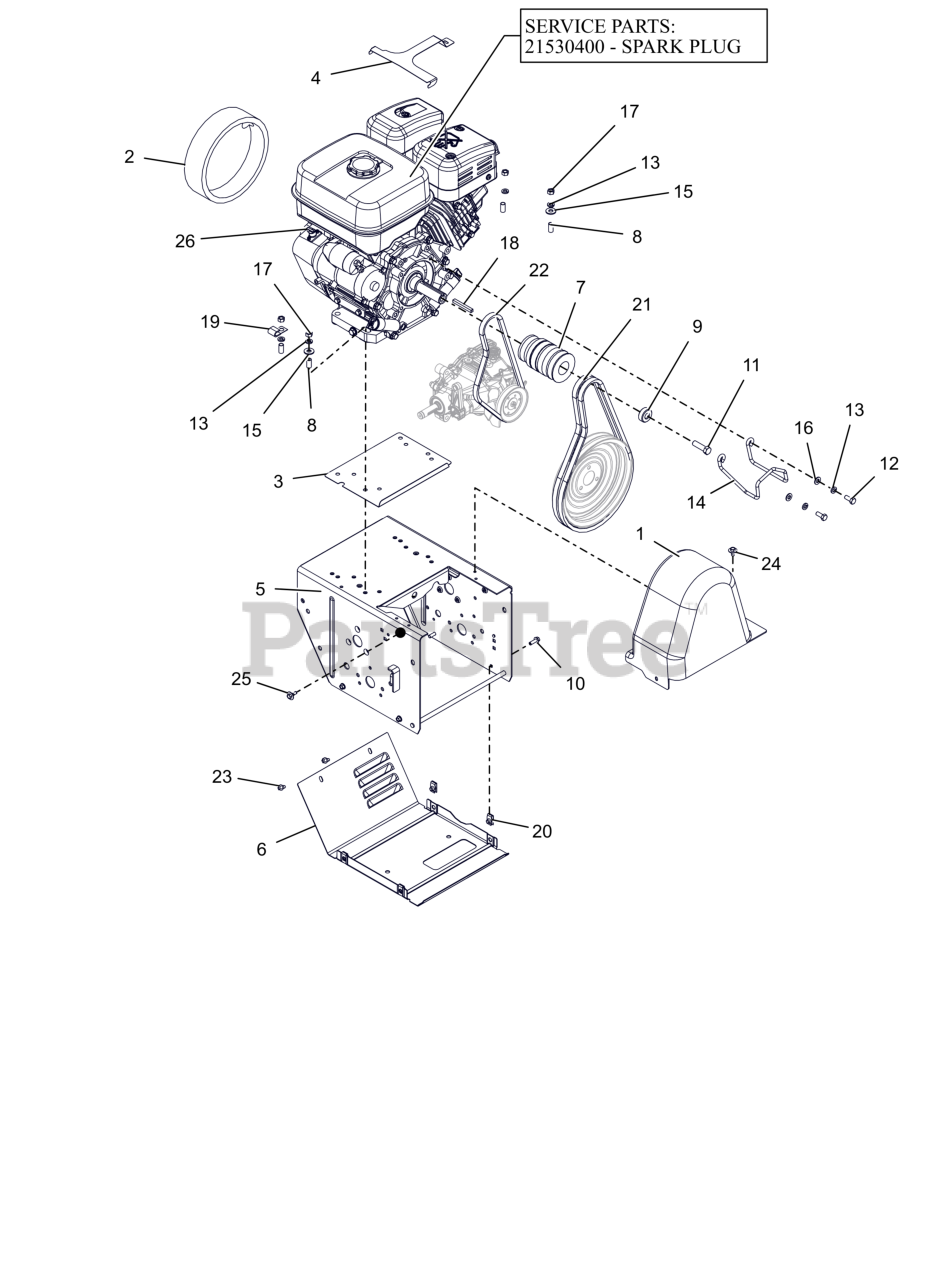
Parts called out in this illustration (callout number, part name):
1	COVER, BELT-TALL PRO
2	FOAM COVER, RECOIL-SUBARU
3	BAFFLE, WATER-PRO SERIES
4	GUARD, SNOW-SUBARU
5	PRO HYDRO FRAME, MAIN
6	COVER, BOTTOM - VENTILATED
7	SHEAVE, COMBO HYDRO BRUSH
8	BSHG-SLV .325X.400X.795
9	BSHG-SPACER .47X1.25X.50
10	BLT-HEX .25-20X.75 HWH YZ GR5
11	BLT-HEX .44-20X1.50 G5 YZ EP80
12	BLT-HEX .31-24X.75 YWZC GR5
13	WSHR-LK .312X.097 HVY YWZC
14	FINGER, BELT
15	@WSHR-FL-STL.38X.875X.083 YWZC
16	@WSHR-FL-STL.344X.688X.065YWZC
17	@NUT-HEX .31-18 YWZC
18	KEY .25X.25X2.25
19	J-CLAMP
20	NUT-RTNR .25-20X.56
21	V-BELT, HA-RAW EDGE (SET)
22	V-BELT, 4L-WRAPPED
23	SCR-TAP .25-20X.50 HWH TR YWZ
24	SCR-TAP .25-20X.50 LGHWH TR YZ
25	SCR-TAP .25-20X.5 CAPTIVE
26	ENGINE,SUBARU EX30 AS 12V
26	PLUG, SPARK - TEC. SNO-THRO
